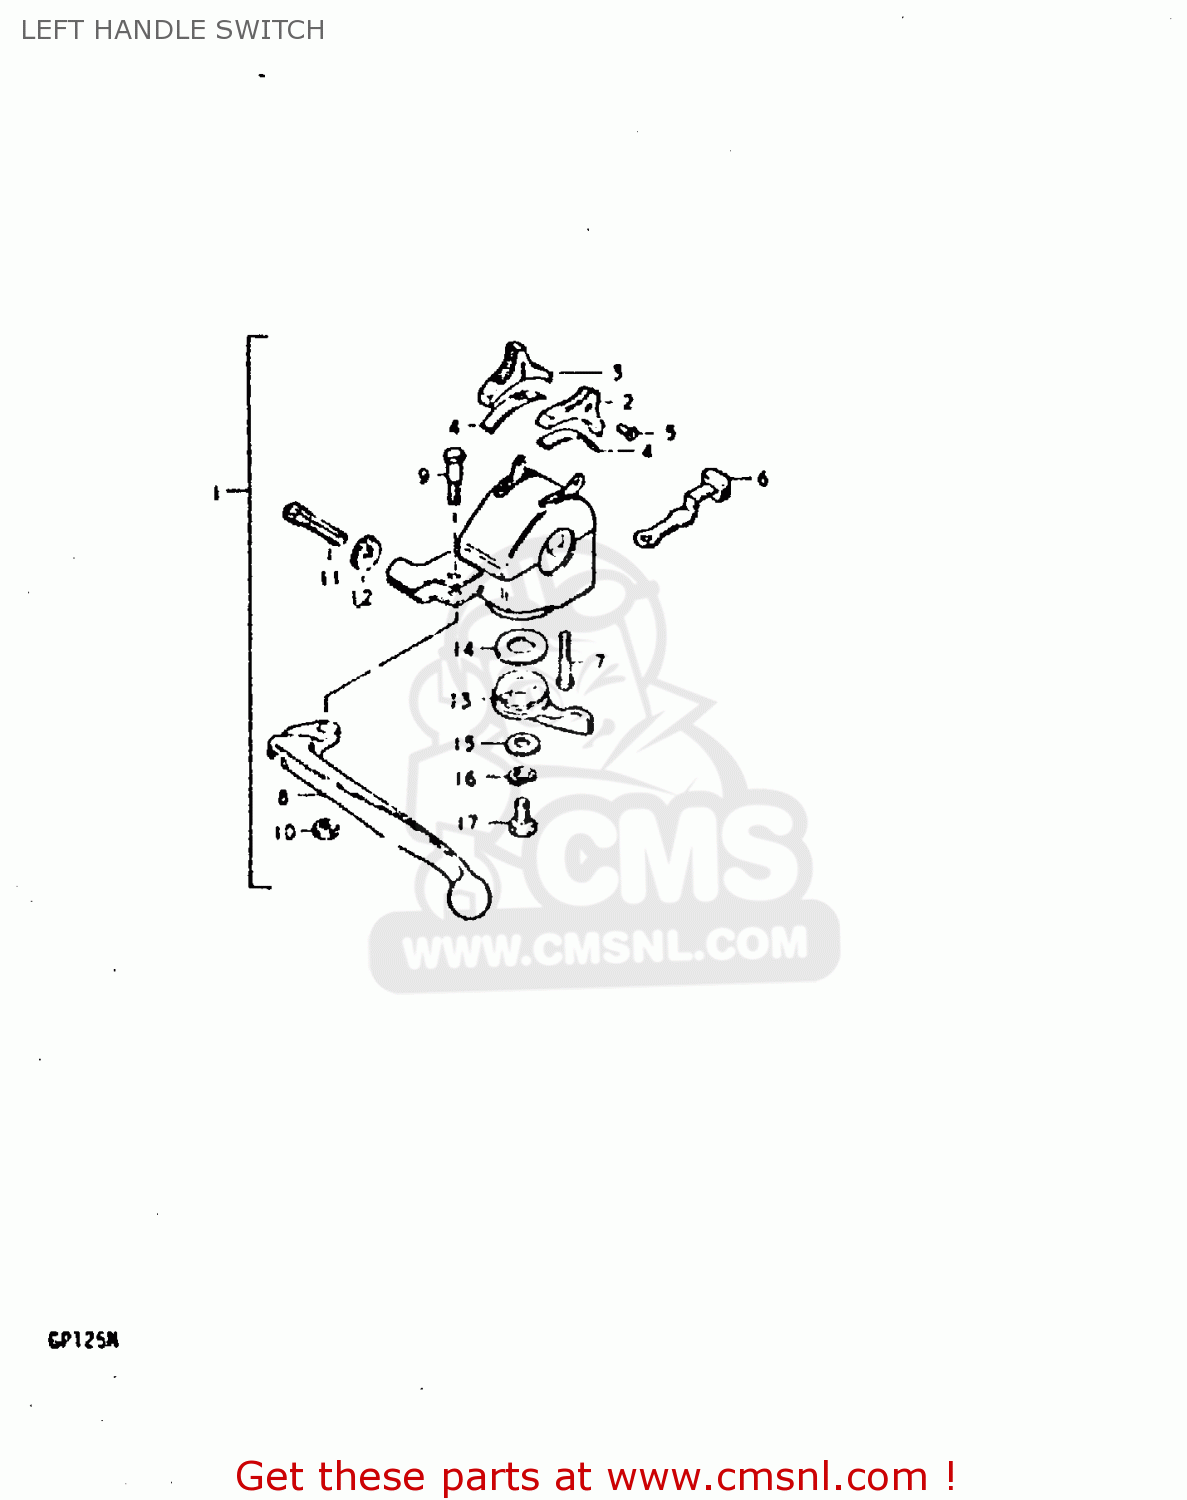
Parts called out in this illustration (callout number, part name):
1	CLUTCH LEVER & SWITCH ASSY
2	KNOB,HANDLE SWITCH
3	KNOB,HANDLE SWITCH
4	PLATE,SWITCH KNOB
5	SCREW
6	LEVER,TURN SIGNAL
7	SCREW 5X20
8	LEVER,CLUTCH
9	BOLT
10	NUT 6MM
11	ADJUSTER,CABLE
12	NUT,CABLE ADJUSTER
13	LEVER,STARTER
14	WASHER,ADJUSTER
15	WASHER,STARTER LEVER
16	LOCK WASHER
17	BOLT
